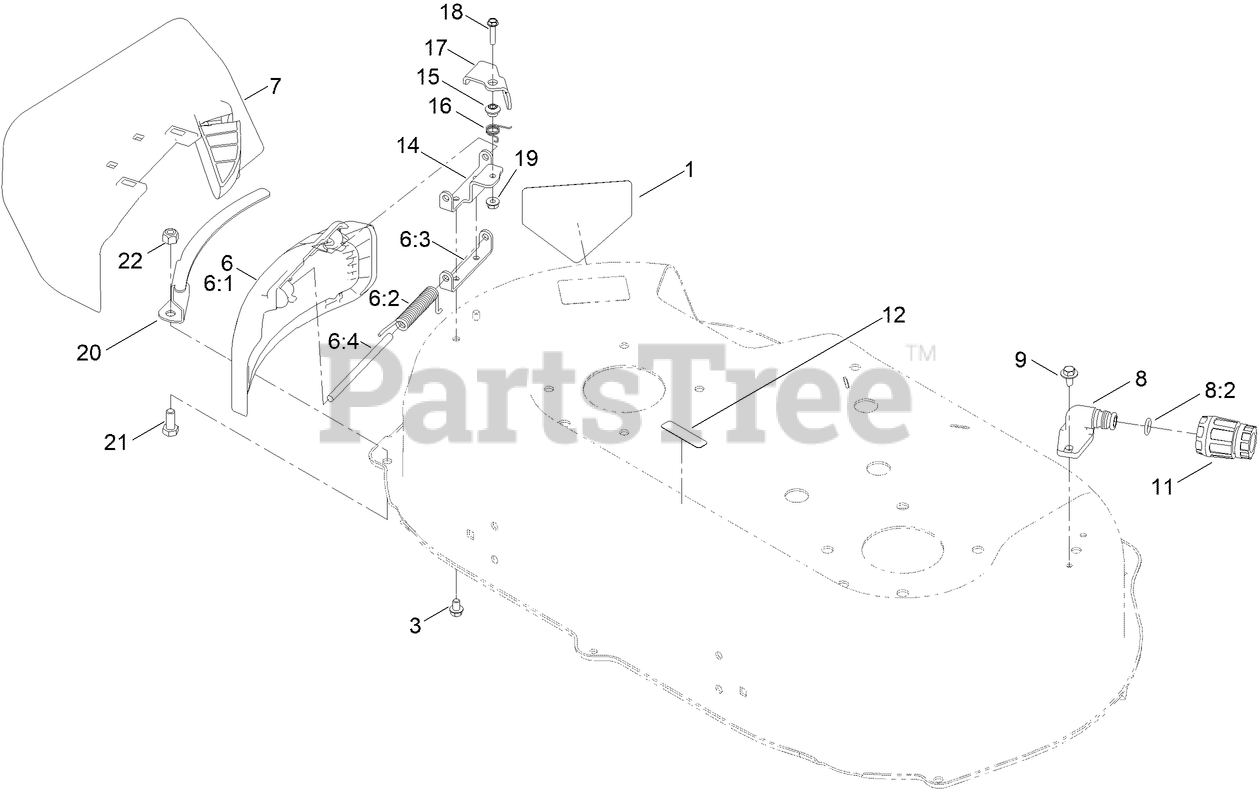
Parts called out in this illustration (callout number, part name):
1	DECAL-DANGER
6	SIDE DEFLECTOR SERVICE ASM
6:1	DEFLECTOR-DISCHARGE, SIDE
6:2	SPRING-TORSION, COVER
6:3	BRACKET-LOCKOUT
7	SIDE DISCHARGE CHUTE ASM
8	FITTING-WASHOUT
8:2	O-RING
9	SCREW-HWH, THD ROLL
11	CONNECTOR-HOSE
12	DECAL-WARNING
14	BRACKET-LOCKOUT
15	SPACER
16	SPRING-TORSION
17	LEVER-LOCKOUT
18	SCREW-HWH
19	NUT-HEX FLANGE
20	BRACKET-DOOR, SIDE
21	SCREW-HH
22	NUT-HEX
